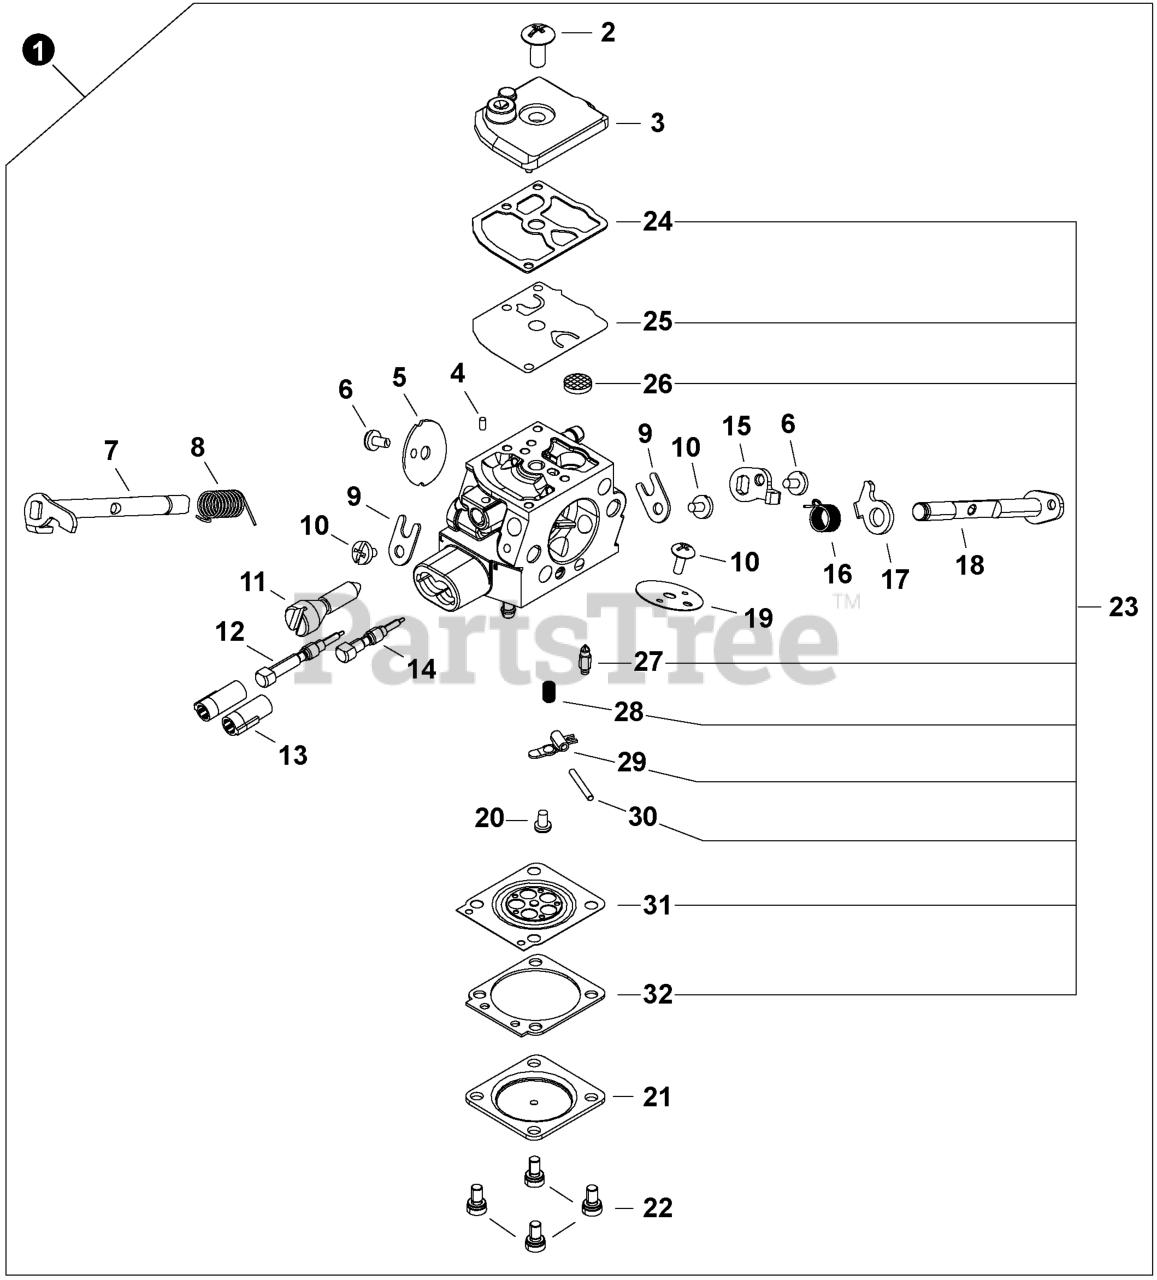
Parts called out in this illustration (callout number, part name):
1	CARBURETOR GC-03-1
2	SCREW
3	COVER, FUEL PUMP
4	PIECE, FRICTION
5	VALVE, THROTTLE
6	SCREW
7	SHAFT, THROTTLE
8	SPRING, THROTTLE
9	CLIP, SHAFT
10	SCREW
11	SCREW
12	NEEDLE, LOW SPEED
13	CAP, LIMITER
14	NEEDLE, HIGH SPEED
15	LEVER, THROTTLE
16	SPRING
17	LEVER, FAST IDLE
18	SHAFT, CHOKE
19	VALVE, CHOKE
20	SCREW, METERING LEVER PIN
21	COVER, METERING DIAPHRAGM
22	SCREW
23	REPAIR KIT, CARBURETOR
24	GASKET, FUEL PUMP
25	DIAPHRAGM, PUMP
26	SCREEN, FUEL INLET
27	VALVE, INLET NEEDLE
28	SPRING, METERING LEVER
29	LEVER, METERING
30	PIN, METERING LEVER
31	DIAPHRAGM, METERING
32	GASKET, METERING DIAPHRAGM
